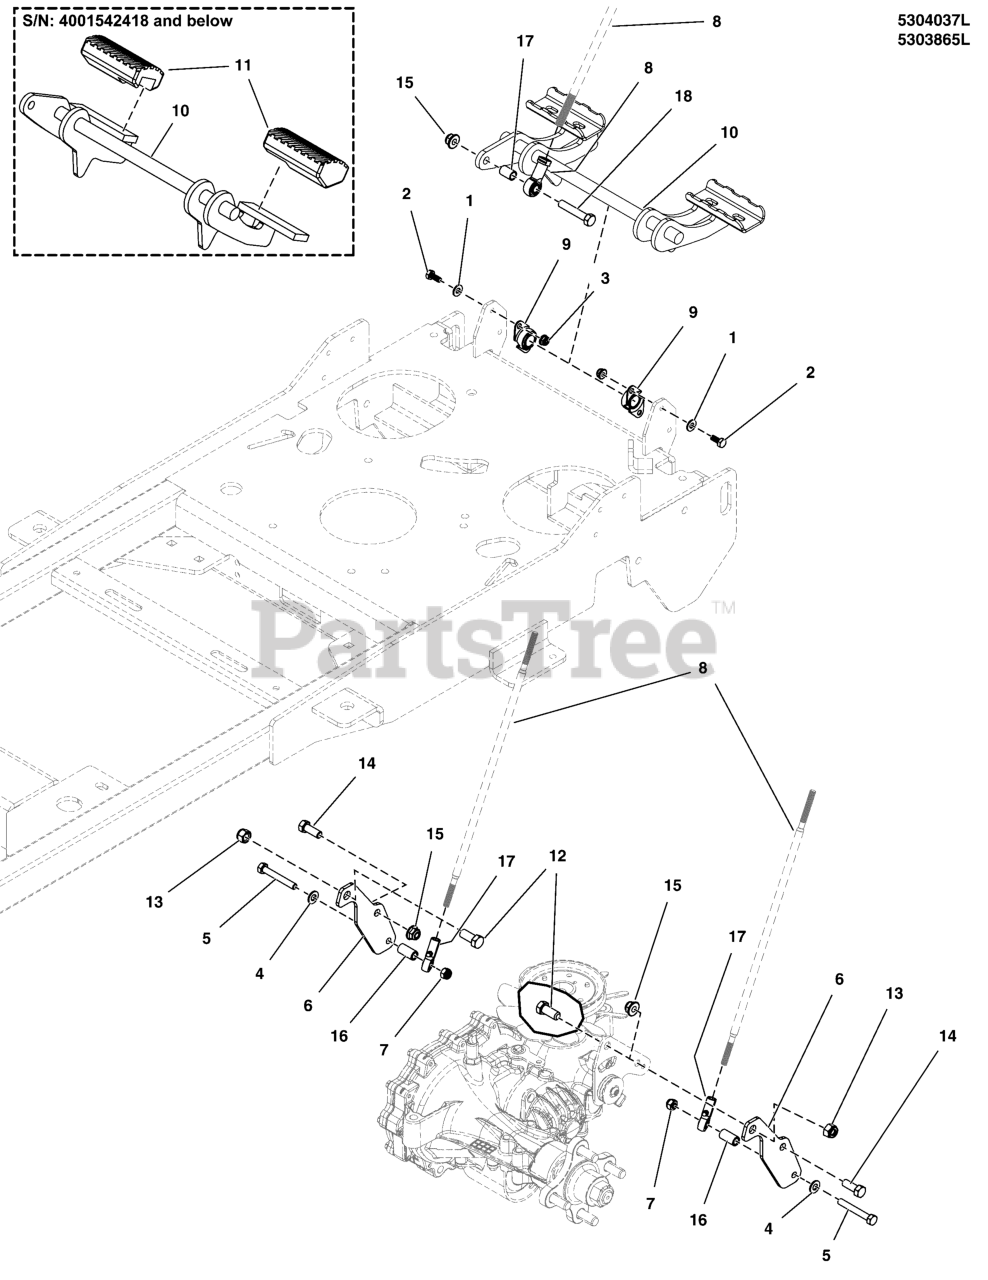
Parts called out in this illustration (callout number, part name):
1	WASHER, 1/4 SAE
2	HHCS, 1/4-20 X 0.625, GR5, ZINC/CLEAR
3	NUT, 1/4-20 Hex Nylock Flange
4	WASHER, 5/16" SAE
5	BOLT, 5/16-18 X 2-1/4" GD5 YZ
7	NUT, Hex, Nylon Locking, 5/16-18
8	SEE MOTION CONTROL UPPER GROUP
9	BEARING, 5/8" FLANGED, PLASTIC BALL
10	WELD, FOOT PEDAL - BLK
11	PEDAL, Rubber
12	BOLT, 7/16-14 X 3/4, GD 5 YZ
13	NUT, 7/16-14 HEX TOP LOCK
14	BOLT, 3/8-16 X 1" GD5 CZ
15	NUT, 3/8 - 16 HEX NYLOCK FLANGE
16	SPACER (.325 X .496 X 1.000)
17	SPACER, .38 x .50 x .75
18	BOLT, 3/8-16 X 2, GD5, CZ
